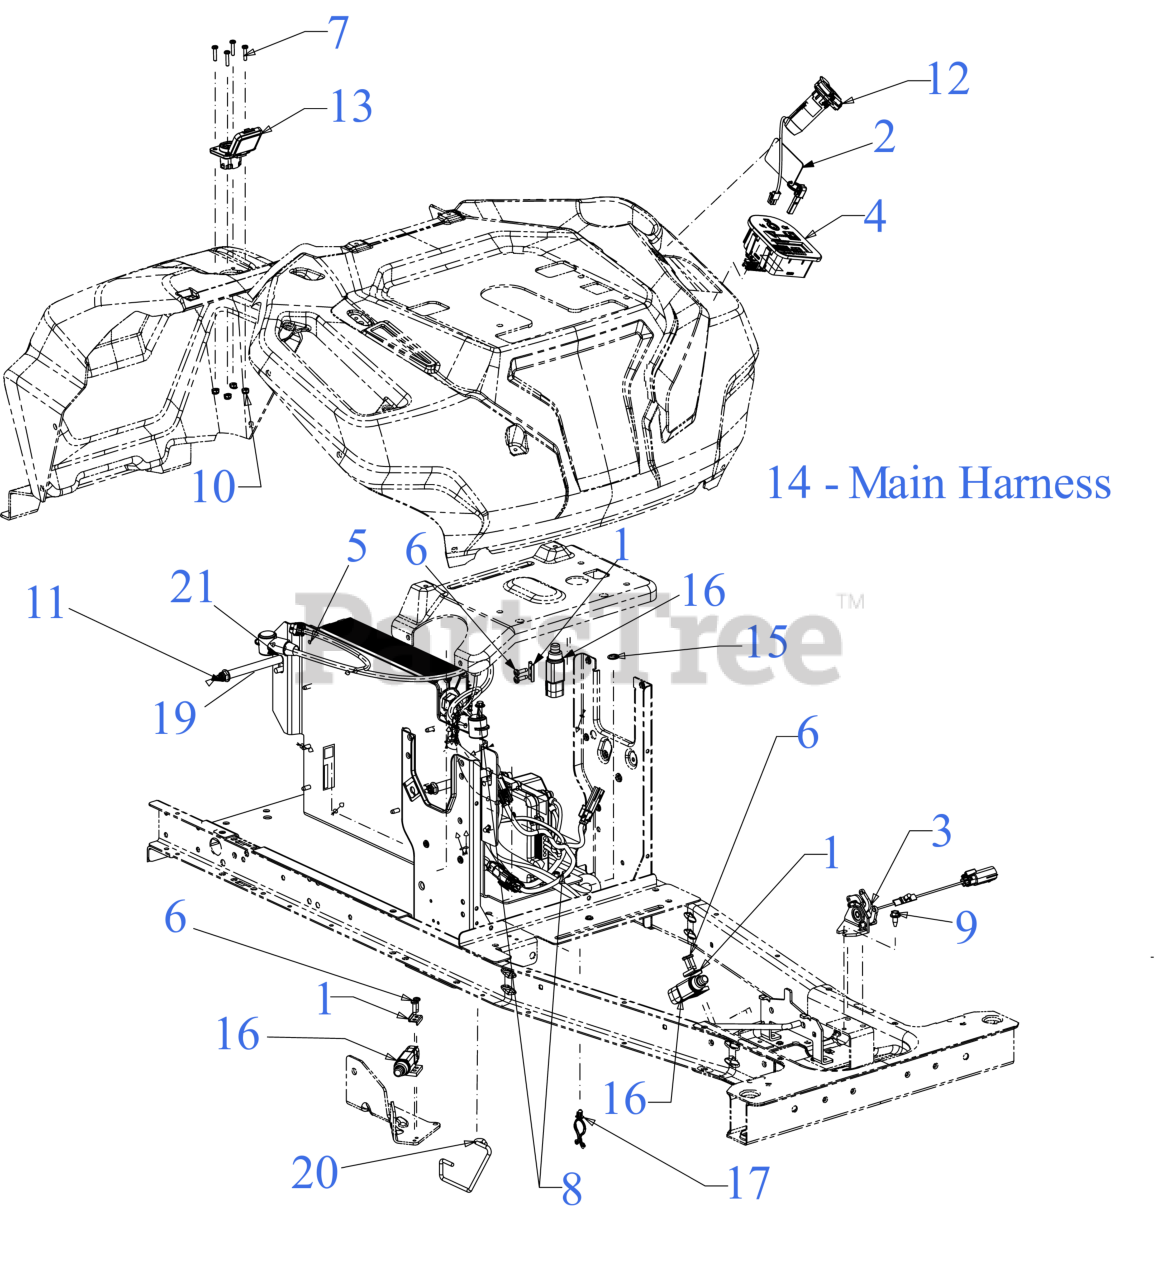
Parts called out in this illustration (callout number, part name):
1	PLATE-SWITCH
2	MAGNETIC KEY
3	THROTTLE SENSOR ASSEMLBLY
4	VCM SWITCH ASSEMBLY
5	Not Serviceable/ Components Only
6	SCREW #10-24X11/16 T-25
7	SCREW #8-32 x .750
8	SCREW M6-1 x .625
9	SCREW 1/4-20X.625
11	FLANGE LOCK NUT 5/16-18
12	USB RECEPTACLE (12V W/JUMPER)
13	CHARGER PORT HARNESS (8-PIN)
14	MAIN HARNESS (VCM/SPDM)
16	SEALED PLUNGER SWITCH
17	TWIST LOCK CLIP
19	BATTERY ROD 5/16-18
20	DECK CABLE SUPPORT ROD
21	SPACER .322 x .438 x 3.855
